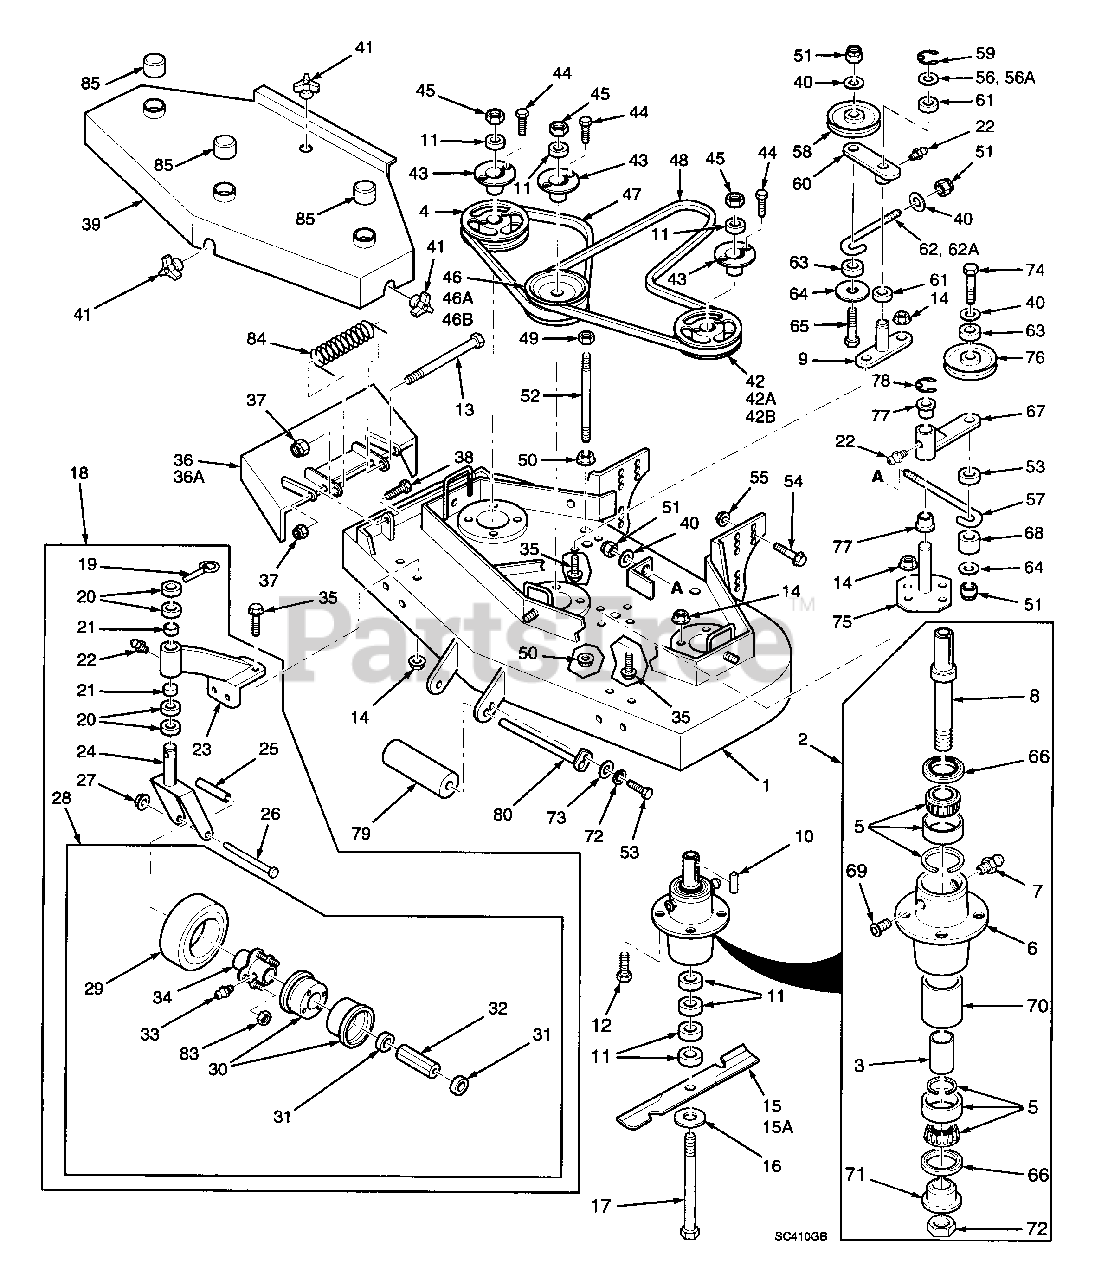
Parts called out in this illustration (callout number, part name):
1	Cutter Deck
2	Spindle Assembly
3	Spacer, Inside
4	Pulley
5	Tapered Bearing
6	Spindle Housing
7	Grease Fitting Str. 5/16
8	Spindle Shaft, Tapered Bearing
9	Idler Pivot
10	Key, 1/4 x 1/4 x 2"
11	Spacer, Cutter Blade - Small
12	Bolt, 5/16-18 x 1-1/4" Hex Head
13	Bolt, 5/16-18 x 4-1/4" Hex Head
14	Serrated Flange Nut, 5/16-18
15	Cutter Blade 21"
15A	Cutter Blade 21 Hi Lift
16	Flatwasher, 5/8" .688 x 1.75 x .134
17	Hex Head Bolt, 5/8-11 x 9-1/2"
18	Caster Assembly
19	Quick Pin
20	Spacer, Caster Yoke, 1/2" thick
21	Bronze Bearing
22	Lock Wshr, 5/16" .317 x .586 x .078
23	Support Assembly,
24	Caster Yoke
25	Sleeve, Caster Wheel Bearing
26	Hex Hd Bolt, 1/2-13 x 5-1/2"
27	Elastic Stop Nut, 1/2-13
28	Wheel Assy
29	Tire only, Caster Wheel
30	Rim Pair, Caster Wheel
31	Bearing Retainer, Caster Wheel
32	Roller Bearing, Caster Wheel
33	Grease Fitting 45 deg., 1/4-28
34	Hub Assembly
35	Capscrew, 5/16-18 x 3/4"
36	Discharge Chute
36A	Discharge Chute
37	Nut, 5/16-18 Elastic Elastic Stop
38	Bolt, 5/16-18 x 1" Hex Head
39	Belt Cover
40	Flat Washer, 3/8" Special
41	Wing Nut, 3/8-16
42	Pulley
42A	Pulley
42B	Pulley
43	Tapered Hub
44	Bolt, 1/4-20 x 3/4" Hex Head
45	Nut, 5/8-11 Hex
46	Pulley, Double
46A	Pulley, Double
46B	Pulley, Double
47	Belt, RH Blade Drive
48	Belt, Blade Drive
49	Nut, 3/8-16, Nut Centerlock
50	Nut, 3/8-16, Serrated Flange
51	Nut, 3/8-16, Elastic Stop
52	Support, Belt Cover
53	Bolt, 5/16-18 x 1/2" Hex Head
54	Cpscrw, 7/16-14 x 1" Ser. Flng H Hd
55	Nut, 7/16-14 Serrated Flange
56	Flat Washer 3/4" Special
56A	Flat Washer 3/4" Special
57	J-Hook
58	Idler Pulley, "V" Groove
59	Retaining Ring, 3/4" Ext "E"
60	Idler Arm Assy.
61	Bronze Bearing
62	J-Rod, Idler Pulley
62A	J-Rod, Idler Pulley
63	Spacer, J-Rod
64	Washer, 3/8 x 1-1/2 x 16 ga.
65	Bolt, 3/8-16 x 2-1/4" Hex Head
66	Seal, Cutter Spindle
67	Idler Arm Assy
68	Spacer, J-Rod
69	Relief Fitting, Cutter Spindle
70	Spacer, Outside, Cutter Spindle
71	Spindle Bushing
72	Nut, Cutter Spindle
73	Flat Wash, 5/16" .375 x .875 x .083
74	Bolt, 3/8-16 x 3-1/2" Hex Head
75	Idler Pivot
76	Idler Pulley, Belt Clutch
77	Bronze Bearing
78	Retaining Ring
79	Guide Roller
80	Roller Shaft
81	Seal, Cutter Spindle
82	Spacer, J-Hook
83	Nut, 3/8-24 Tapered
84	Spring, Chute Return
85	Spindle Shield
